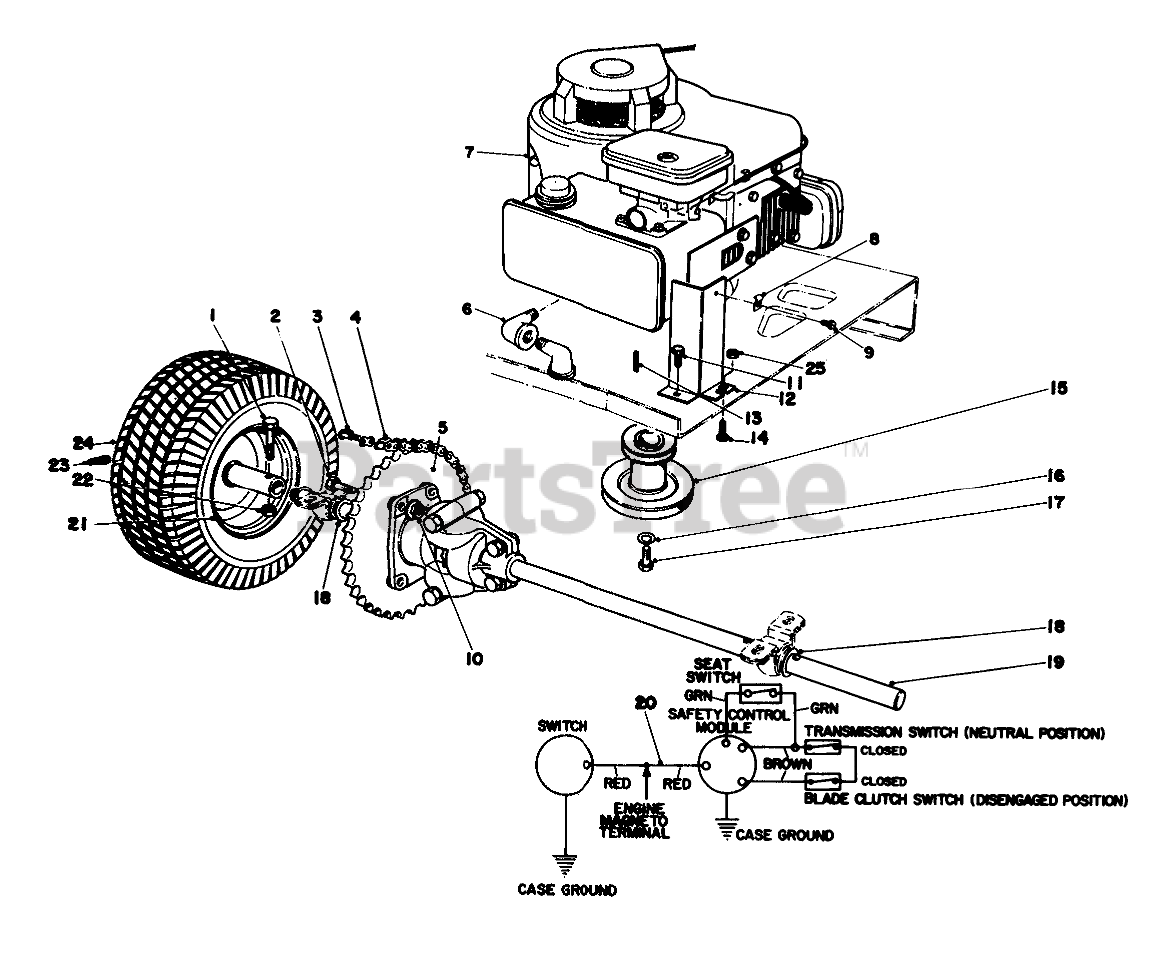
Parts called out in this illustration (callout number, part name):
1	SCREW-HH
2	SCREW-HH
3	LINK-CONNECTING
4	ROLLER CHAIN
5	Sprocket
6	90deg. Street Elbow
7	Engine
9	Screw
10	NUT-LOCK, CONE
11	SCREW-HWHTF
12	Support-Wire
14	5/16-18X5/8 TRS HD MS
15	ENGINE SHEAVE
16	WASHER-LOCK
17	SCREW-HH
18	WASHER
19	Differential
20	Wiring Harness
22	NUT-LOCK, CONE
23	STEM-VALVE
24	Tire
25	NUT-KEPS
